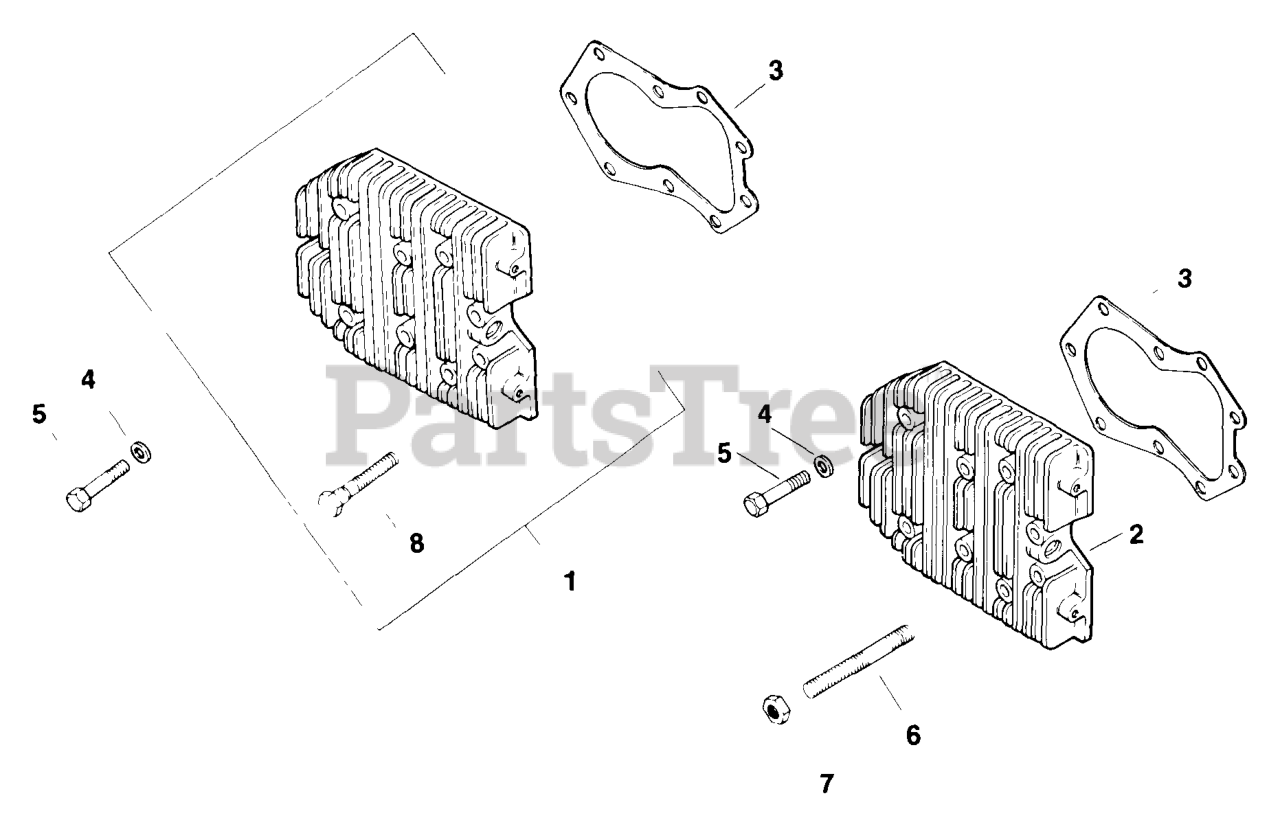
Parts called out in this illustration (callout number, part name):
1	Kit, Cylinder Head
3	Gasket, Head
4	Washer, Plain 5/16"
5	Screw, Hex. Hd. 5/16-18x1-1/2"
6	Stud 5/16-18x2"
7	Nut, Hex. 5/16-18"
8	Screw, Hex. Mach. 5/16-18x2"
